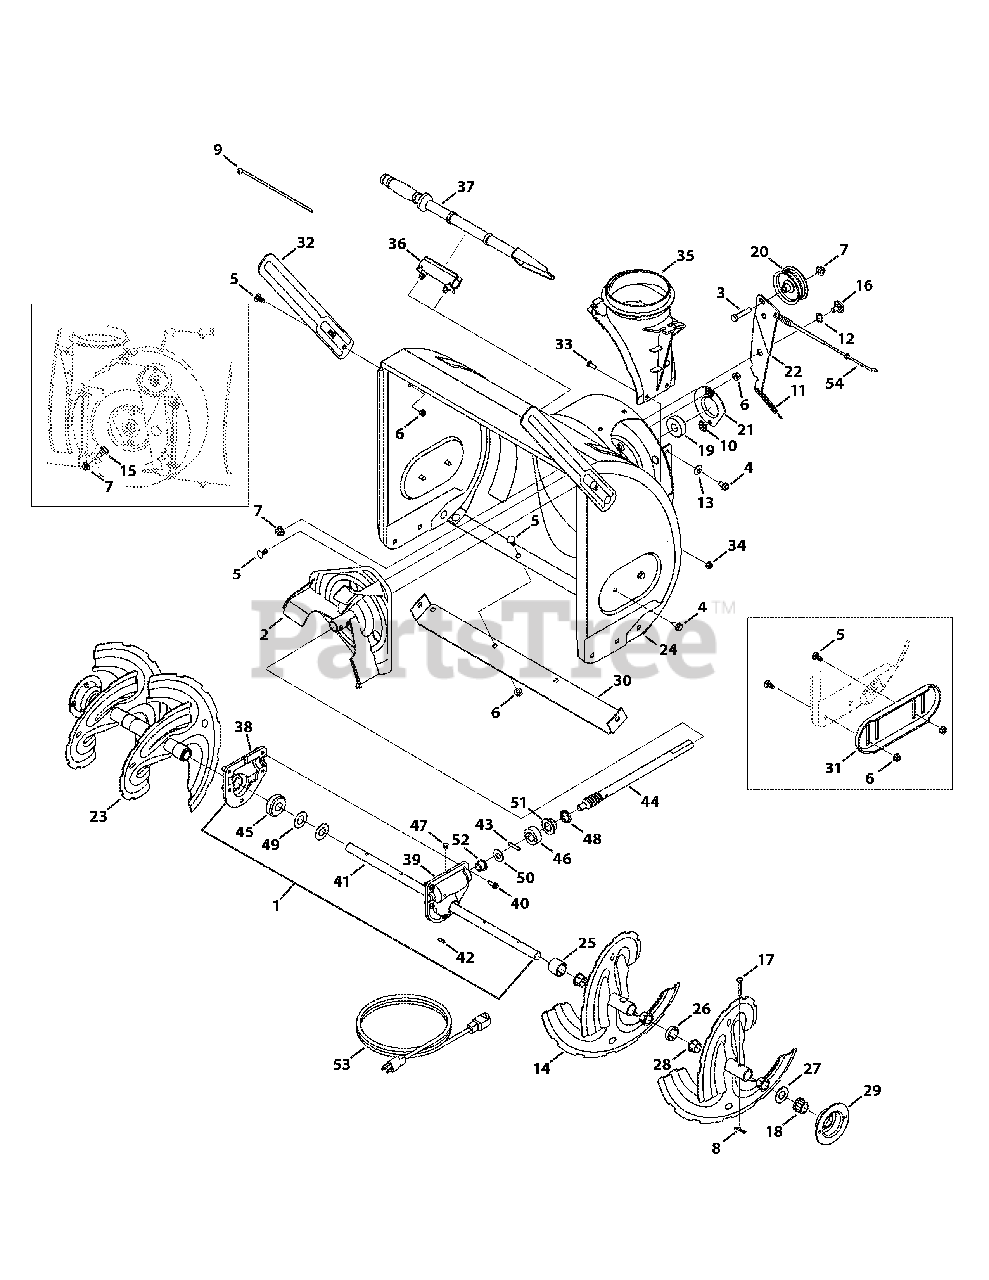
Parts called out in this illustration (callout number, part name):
1	Auger Gearbox Assembly
2	Impellor Assembly, 12" DIA
3	Hex Head Screw, 3/8-16 x 1.75
4	Screw, 5/16-18 x .750
5	Bolt, Carriage, 5/16-18 x .750
6	Nut, Flangelock, 5/16-18
7	Nut, Flangelock, 3/8-16
8	Bow-Tie Cotter Pin
9	Cable Tie, 3/16 x .05 x 7.4
10	Nut, Push-on, .25 DIA
11	Extension Spring, .38 OD x 4.59
12	Washer, Wave, .625 x .885 x .015
13	Washer, Bell, .340 x .872 x .060
14	Spiral Assembly, LH - Gray
15	Bolt, Shoulder, .496 x .336 x 3/8-16
16	Screw, Shoulder, .625 x .17 x 3/8-16
17	Shear Pin, .25 x 1.50
18	Bearing, Hex Flange, .75 ID
19	Bearing, Ball, .75 ID x 1.85 OD
20	Pulley, Idler, Flat, 2.75 OD
21	Bearing, 1.85 ID
22	Auger Idler Bracket
23	Spiral Assembly, RH - Gray
24	Auger Housing Assembly,
25	Spacer, 1.25OD x .75ID x 1.00 LG
26	Spacer, 1.25OD x .75ID x 3/16 LG
27	Washer, Flat, .76 x 1.49 x .06
28	Bushing, Flange, .800 ID x .910 OD
29	Bearing, 1" Hex
30	Shave Plate, 2.25 x 29.66 LG - Black
31	Deluxe Shoe Slide - Black
32	Blade Guide
33	Screw, Carriage, 1/4-20 x .75
34	Nut, Flangelock, 1/4-20
35	Chute Adapter
36	Cleanout Tool Mount
37	Cleanout Tool
38	Reducer, RH
39	Reducer, LH
40	Screw, 1/4-20 x 0.750
41	Auger Axle, 30"
42	Key, Hi-Pro, 3/16 x 5/8
43	Dowel Pin, .25 OD x 1.25 LG
44	Worm Shaft, .75 OD
45	Gear Worm, 20T
46	Collar Thrust, .756 ID x .600
47	Plug, 1/4 x .437
48	Oil Seal, .75 x 1.131 x .188
49	Washer, Flat, .760 ID x 1.50 OD
50	Washer, Flat, .51 x 1.12 x .06
51	Bearing, Flange, .75 ID x 1.00 x .59
52	Bearing, Flange, .50 ID x .75 x .59
53	Extension Cord, 110V
54	Auger Drive Clutch Cable
